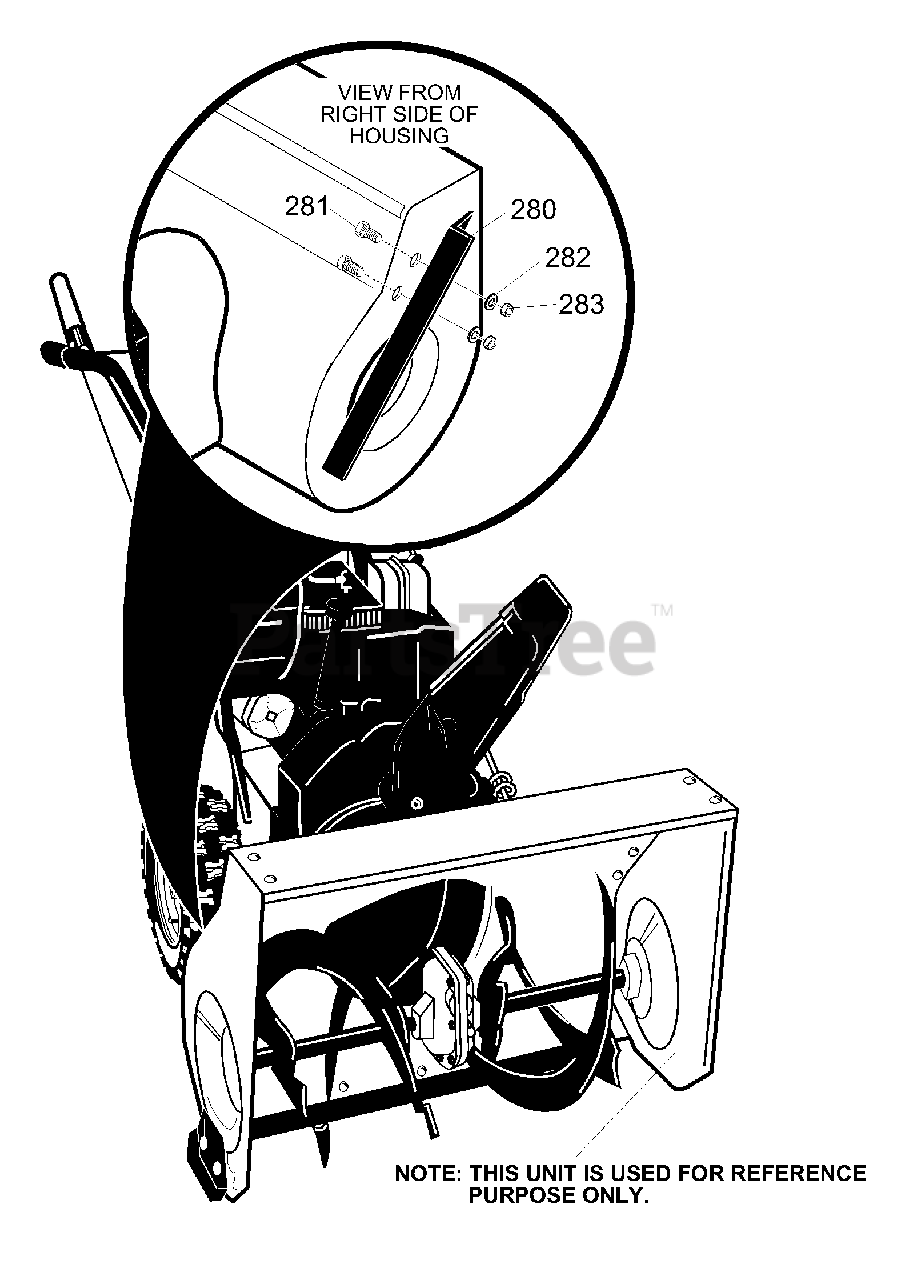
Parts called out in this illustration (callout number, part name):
280	BAR, DRIFT CUTTER
281	BOLT, 5/16-18X.75 CARR.
282	WASHER, HVSPTLK .328X.60X.09
283	NUT, 5/16-18 REGHEX
